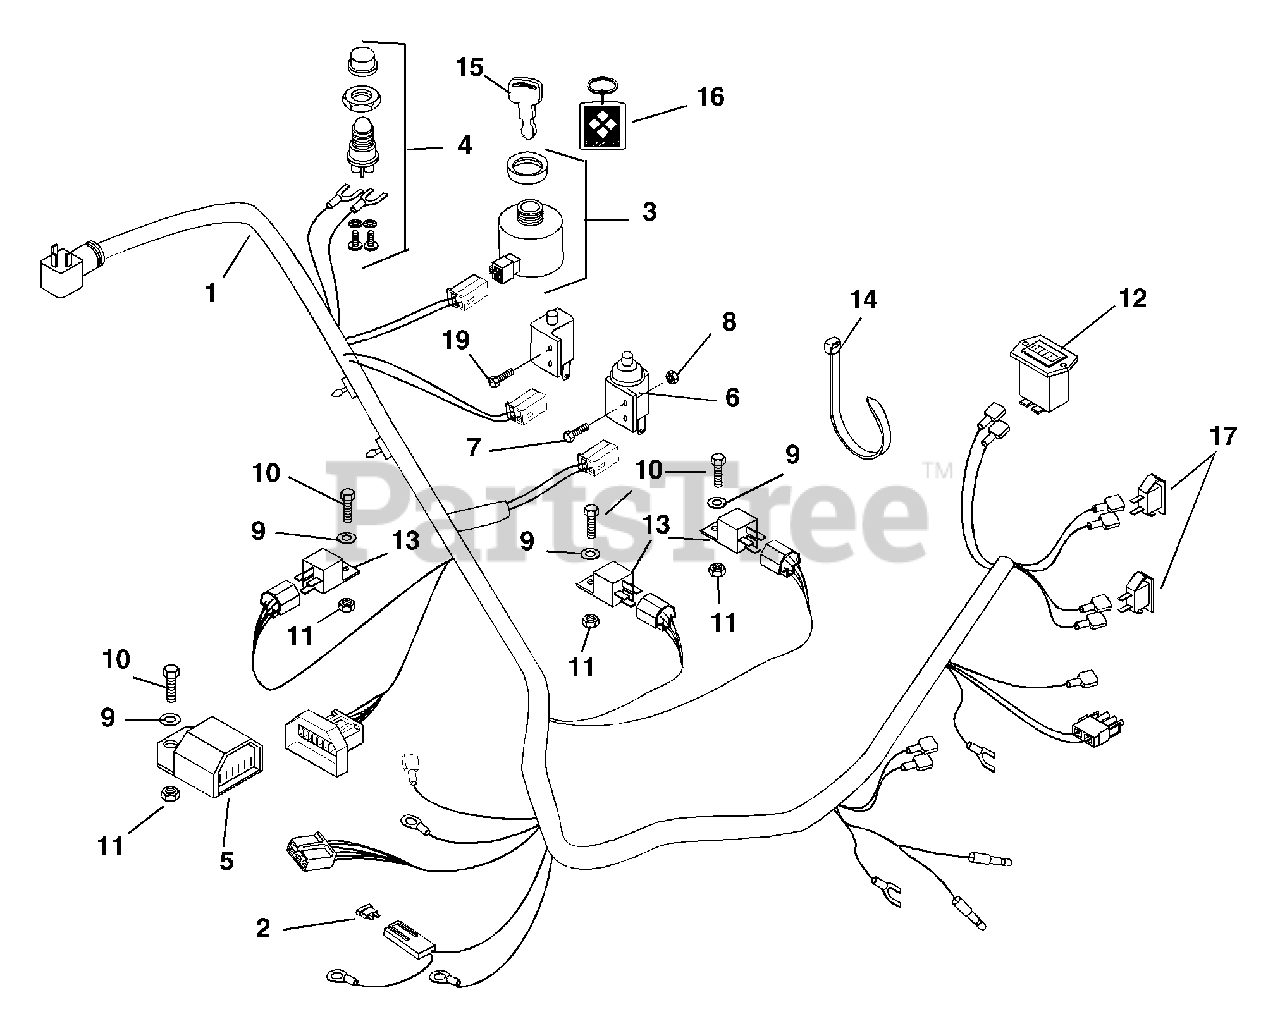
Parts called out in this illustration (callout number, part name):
1	Harness,Wiring 20HP Kubota
2	Fuse-30 Amp
3	Switch-Ignition-Kubota
4	Switch
5	Module-Interlock Delay
6	Switch-Operator Presence
7	Bolt-Hex M5-.8 x 16
8	Nut-Locking-Nylon M5-.8
9	Washer-Flat-Steel .194 x .492 x .047
10	Bolt-Hex M5 x .80 x 16
11	Nut-Locking-Nylon M5 x .80
12	Meter-Hour
13	Relay
14	Cable-Tie Large 5-1/2
15	Key, Ignition
16	Key Chain
17	Light, Indicator
18	Switch, Interlock NC
19	Bolt-Hex M5-.8 x 16
